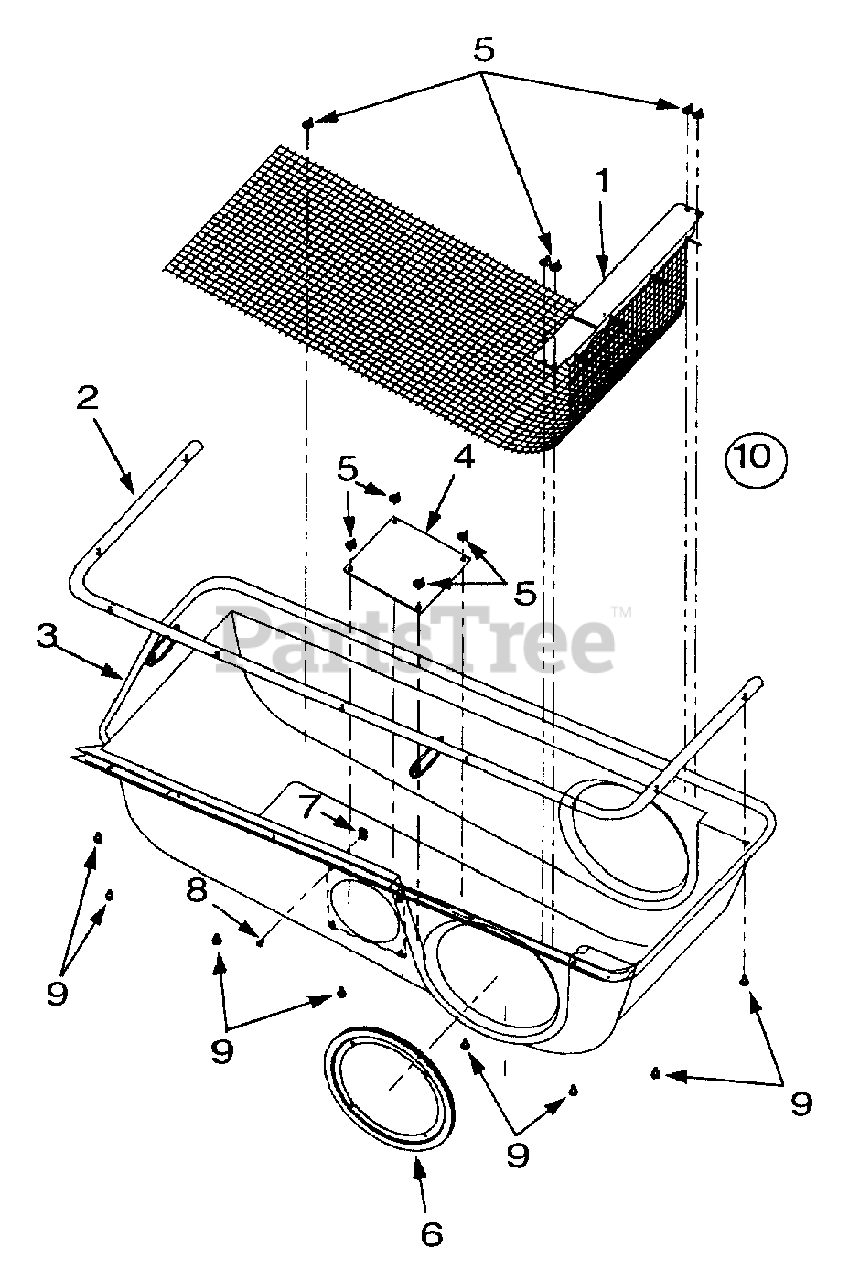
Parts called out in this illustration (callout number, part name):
3	Grass Catcher Cover
4	Plastic Plate
5	Zip Twist Fastener
6	Tube Seal
7	U-Type Speed Nut
8	Screw, #10-16 x 0.5"
9	Hex Screw, 1/4-20 x 0.5"
10	Grass Catcher Cover Assembly
